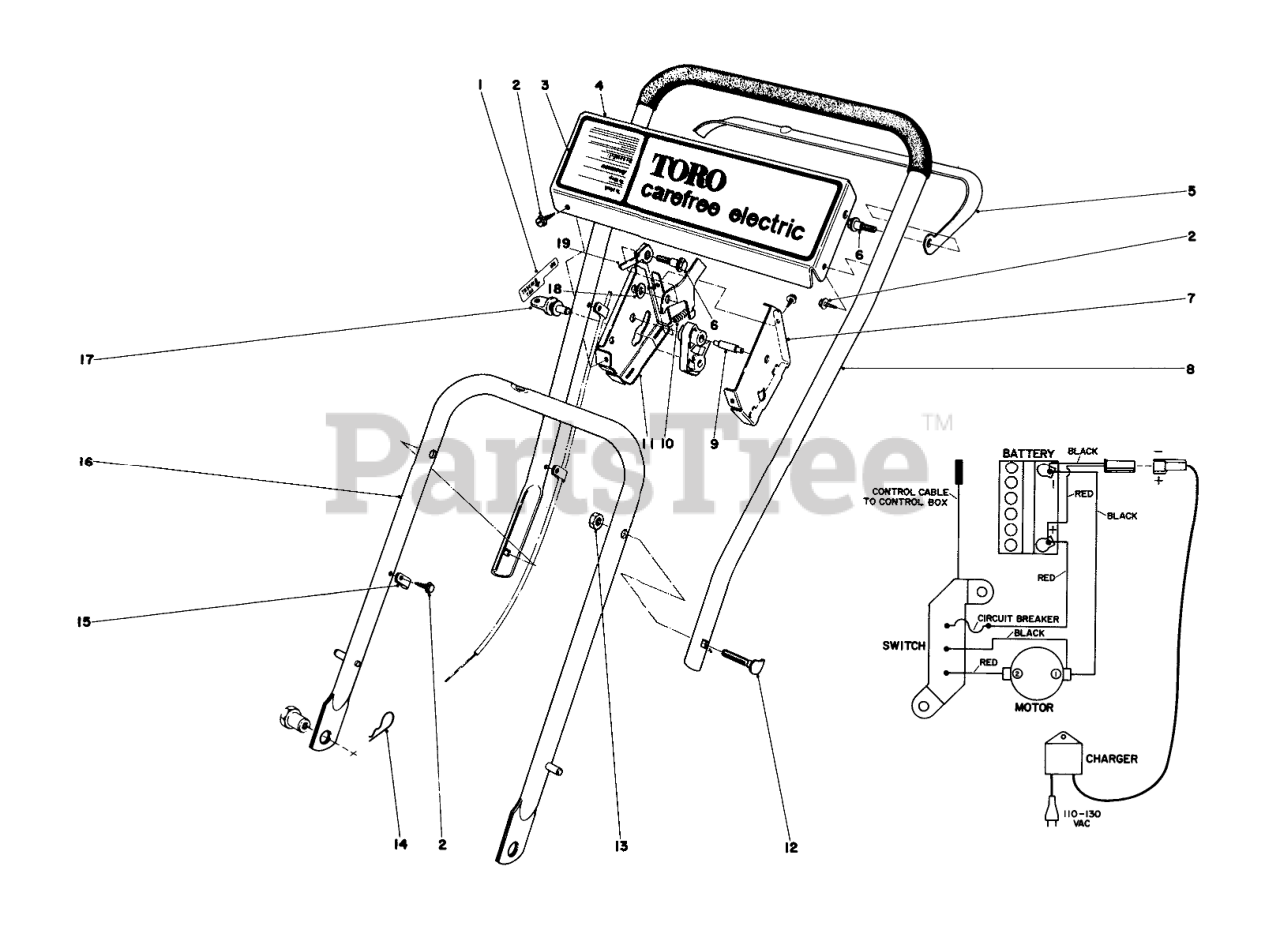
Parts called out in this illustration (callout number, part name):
1	Decal, Control Box
2	SCREW-HWHTF
3	Decal, Control Plate
4	Control Panel
5	Squeeze Lever
6	Shoulder Bolt
7	Cover Control Box
8	Upper Handle
9	Actuator Shaft
10	Spring Extension
11	Control Box
12	HANDLE SCREW
13	Nut
14	PIN-COTTER, HAIR
15	Clamp
16	Lower Handle
18	WASHER-FLAT
19	Latch
